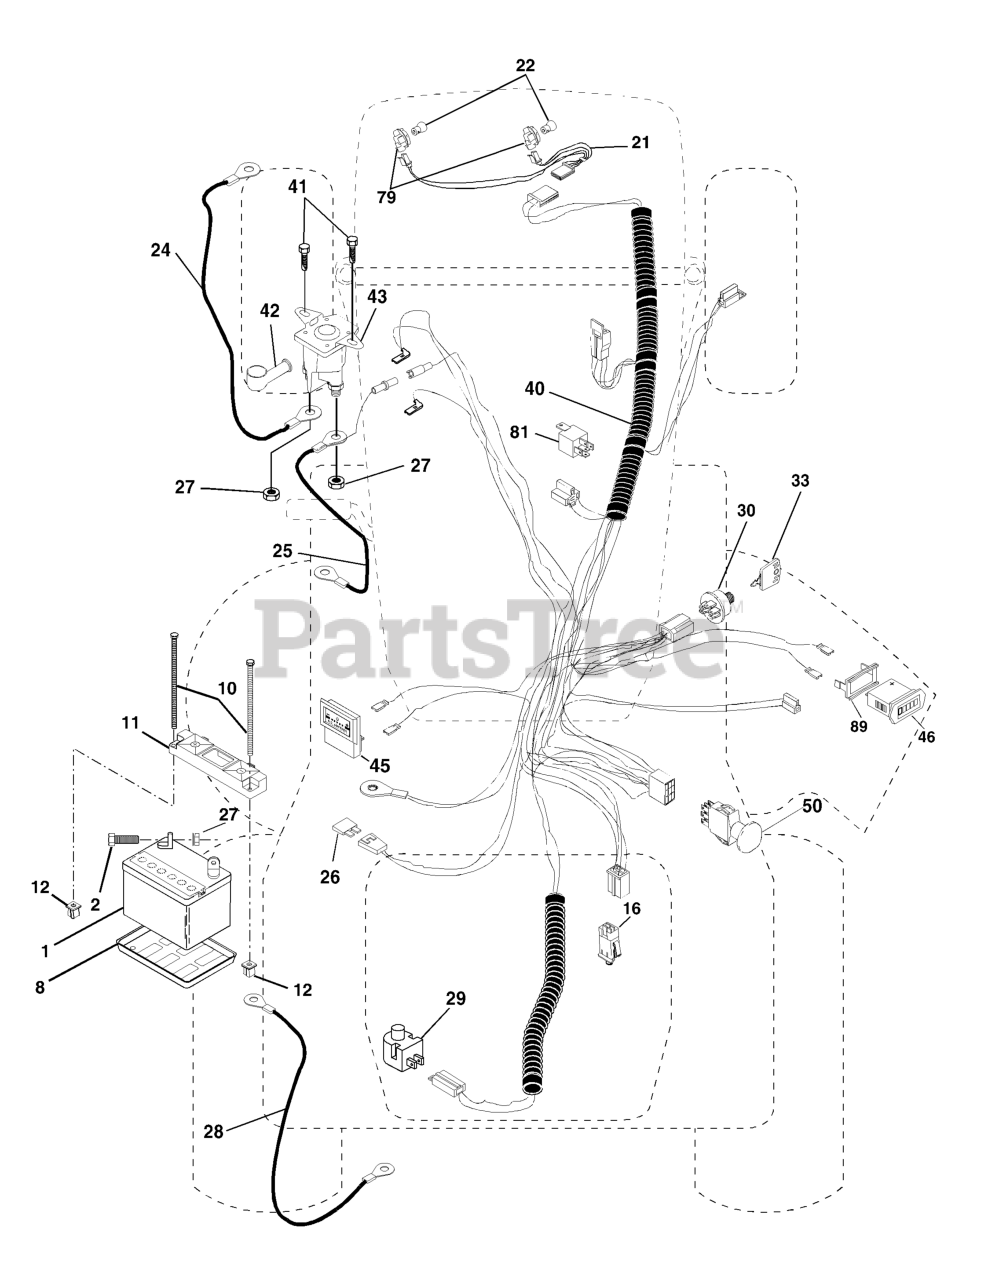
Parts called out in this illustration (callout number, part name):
1	BATTERY
2	BOLT.HEX.1/4.X.3/4.DICHROMATE
8	BATTERY TRAY T
10	BOLT 1/4-20 X 7.5
11	BATTERY HOLDDOWN FRONT MOUNT
12	NUT, PUSH NYLON 1/4" BATTERY
16	SWITCH INTERLOCK
21	HARNESS ASM LIGHT
24	CABLE-BATTERY YTV
25	CABLE, BATTERY
27	NUT
28	CABLE, GROUND
29	PLUNGER SWITCH (COLOR:OLIVE)
30	IGNITION SWITCH
33	KEY MLD GEN DELTA
40	HARNESS, IGNITION
41	SCREW
42	TERMINAL COVER
43	SOLENOID
46	HOUR METER
50	RP.PTO.SWITCH.8 TERMINAL.BLACK
79	BULBHOLDER ASM
81	RELAY.ASSY.T
89	BRACKET SNAP-IN HOURMETER
